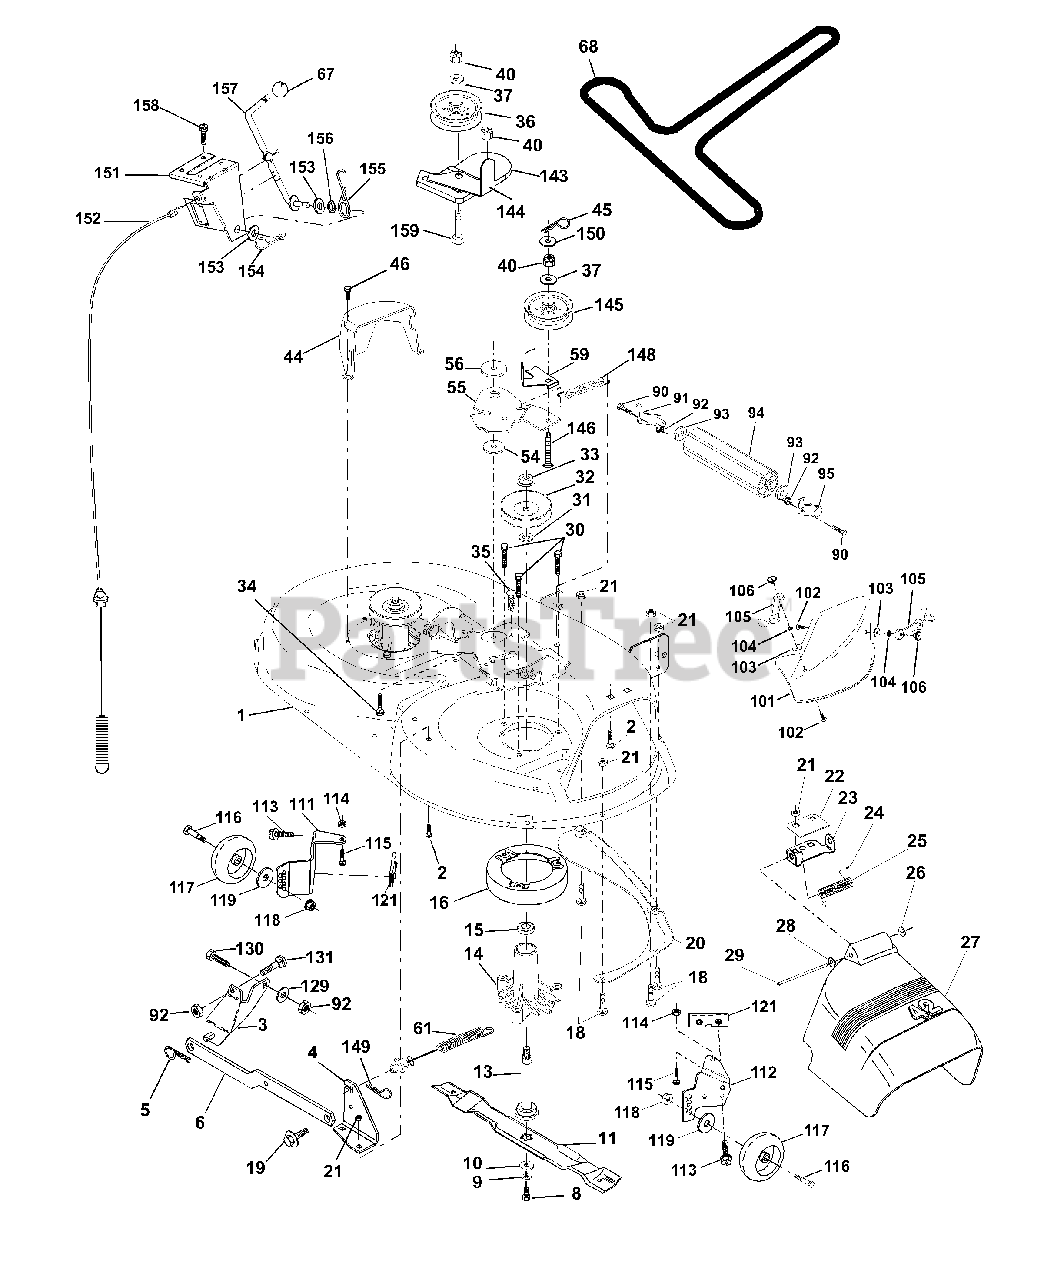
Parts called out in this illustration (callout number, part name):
1	Mower Deck Assembly, 42"
2	Bolt
3	Bracket Asm Fr. Sway Bar 3/42
4	Bracket Asm Deck 42" Sway Bar
5	Retainer Spring
6	Arm, Suspension, Rear
8	Bolt 3/8-24 x 25 Grade 8 patched
9	Washer, Lock
10	Washer,Hardened
11	Blade, Mulching 42" Std
11	Blade Mower 42" Hi-Lift Std
13	Shaft Assembly, Mandrel, Vented
14	Housing, Mandrel, Vented
15	Bearing, Ball, Mandrel
16	Stripper, Mandrel Deck
18	Bolt, Carriage 5/16-18 x 5/8
19	Bolt, Shoulder
20	Baffle, Vortex
21	Nut
22	Stiffener Bracket
23	Bracket, Deflector Mower 42"
24	Cap, Sleeve 80 x 112 Blk Mower
25	Spring, Torsion, Deflector 2 52
26	Nut, Push Phos & Oil
27	Shield, Deflector 42" Blk
28	Washer 11/32 x 5/8 x 16 Gauge
29	Rod, Hinge 42" 6 75 W/G
30	Screw Thdrol Washer Head
31	asher, Spacer Mower Vented
32	Pulley, Mandrel
33	Nut, Toplock 9/16
34	Bolt
35	Fastener, Christmas Tree
36	Pulley, Idler, Flat
37	Washer 13/32 x 13/16 x 16 Gauge
40	Nut
44	Guard, Mandrel, LH
45	Retainer
46	Screw, Thdrol 1/4-20 x 5/8 T
48	Washer, Hardened
49	Roller Assembly, Cam Follower
50	Bolt, Shoulder #10-24 Grade 5
51	Locknut
52	Bolt, Shoulder 5/16-18 UNC
53	Arm Assembly, Pad, Brake
54	Washer, Hardened
55	Arm, Idler
56	Spacer, Retainer
59	Guard TUV Idler
67	Knob Round
68	V-Belt, 42" Mower
90	Bolt Fin Hex 3/8-16 Unc x 1
91	Bracket Asm Noseroller LH
92	Nut, Lock, Hex W/Ins 3/8-16 UNC
93	Washer 17/3 x 7/8 x 6 Ga.
94	Roller Nose 38 & 42
95	Bracket Asm Noseroller RH
101	Mulcher Cover
102	Screw
103	Washer, Flat
104	Washer, Lock
105	Latch Assembly
106	Nut, Weld
111	Bracket, Gauge, Wheel LH
112	Bracket, Gauge, Wheel RH
113	Screw Tapping 5/16 - 18
114	Nut, Keps 5/16 - 18 UNC
115	Bolt, Carriage 5/16-18 x 1/2
116	Bolt, Shoulder
117	Wheel, Gauge
118	Nut Centerlock 3/8-16
119	Washer 3/8 x 7/8 x 14 Ga.
121	Bracket, Extruded
142	Arm Spring Brake Mower
143	Bracket Arm Idler 42"
144	Keeper Belt 42" Clutch Cable
145	Pulley Idler Flat
146	Bolt Carriage Idler
147	Spring Extension
148	Spring Return Idler
149	Retainer Spring Yellow
150	Washer 9/32 x 3/4 x 16 Ga.
151	Bracket Clutch Cable
152	Clutch Cable 42"
153	Washer Flat 3/8" Type B
154	Spring Retainer
155	Spring Retention LVR CLTCH CAB
156	Spacer Clutch Cable
157	Rod Clutch Cable 3/8"
158	Screw Hex Thd Cut 1/4-20 x 5/8
159	Bolt Rdhd Sqn 3/8-16 UNC x 1-3/4
